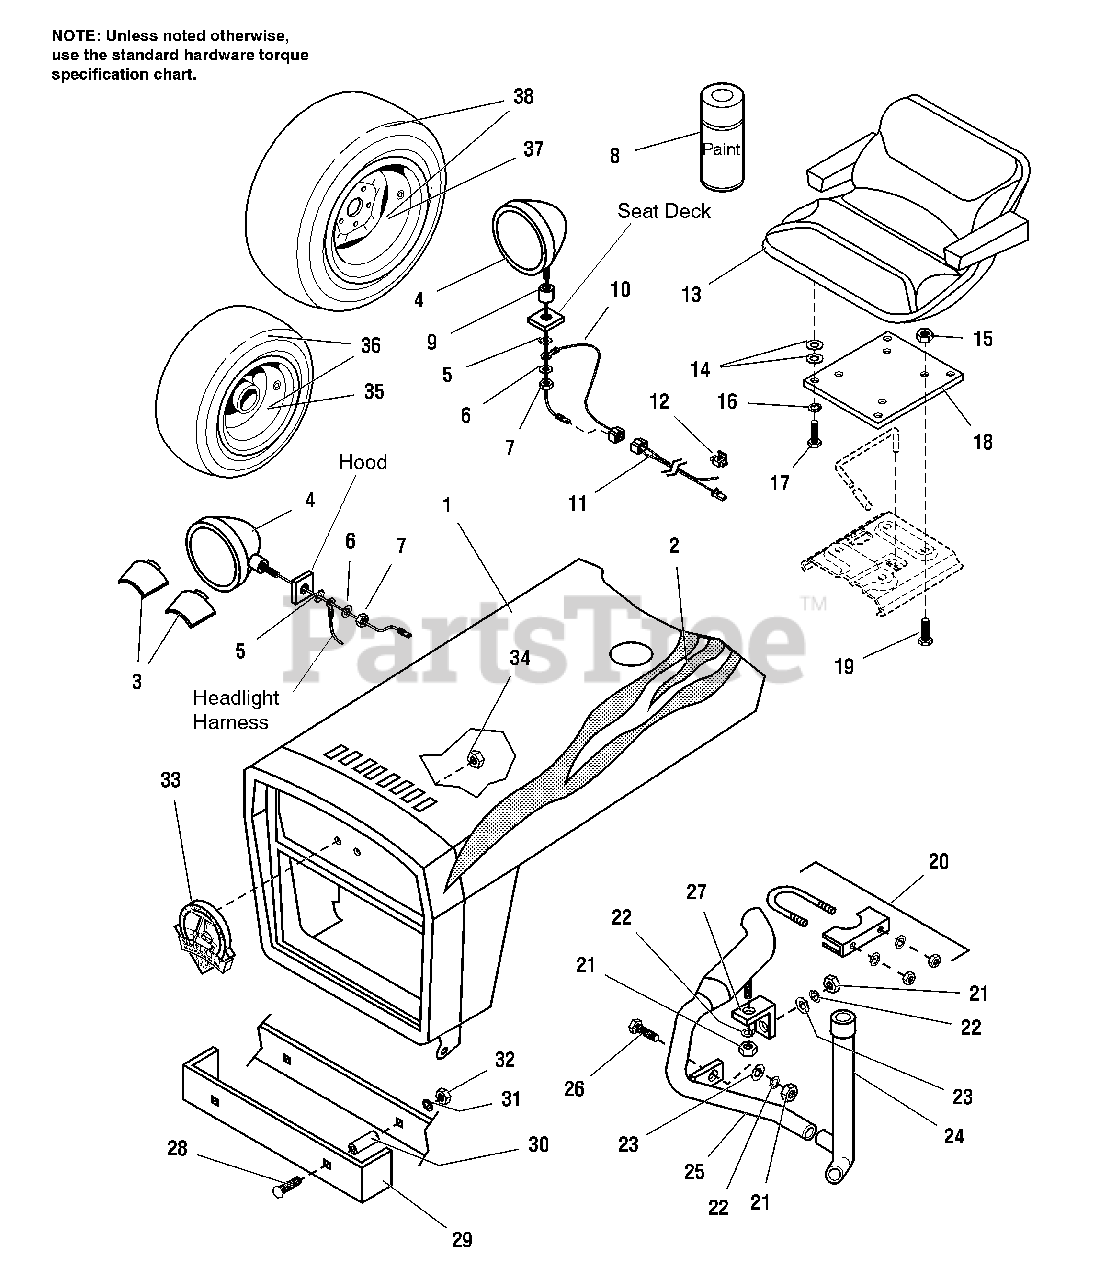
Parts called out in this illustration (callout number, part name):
1	HOOD ASSEMBLY.
2	DECAL, R.H. Hood, Flame
2	DECAL, L.H. Hood, Flame
2	DECAL, Mower
2	DECAL, Rear Seat Deck, "Simplicity"
3	VISOR SET
4	HEADLIGHT-REAR WORKLIGHT ASSEMBLY
5	LOCKWASHER, External Tooth, 3/8
6	WASHER, 3/8
7	NUT, Hex, Full, 3/8-16
8	PAINT, Single Can, 13 oz. Spray Can, Blue
8	PAINT, Case of 12 Cans, 13 oz. Spray Can, Blue
10	WIRE ASSEMBLY, Ground
11	WIRE ASSEMBLY, Work Light
12	CONNECTOR, Splice
13	SEAT ASSEMBLY, with Armrests
14	WASHER, 3/4 x 7/8 x 1/8
15	NUT, Flange, Whizlock, 5/16-18
16	LOCKWASHER, 5/16
17	CAPSCREW, Hex Hd, 5/16-18 x 7/8
18	PLATE, Seat Mounting
19	CAPSCREW, Hex Hd, 5/16-18 x 5/8
20	CLAMP ASSEMBLY
21	NUT, Hex, Full, 5/16-18
22	LOCKWASHER, 5/16
23	WASHER, 11/32
24	ELBOW PIPE, Exhaust
25	PIPE, Exhaust
26	CAPSCREW, Hex Hd, 5/16-18 x 1
27	SUPPORT, Exhaust Pipe
28	CARRIAGE BOLT, 3/8-16 x 3
31	LOCKWASHER, 3/8
32	NUT, Hex, Full, 3/8-16
33	MEDALLION, "75th"
34	NUT, Hex Nylon Lock, 10-24
35	WHEEL ASSEMBLY, Front, Chrome
36	WHEEL & TIRE ASSEMBLY, 16x6.50-8, Chrome, Turf Tread
37	WHEEL ASSEMBLY, Rear, Chrome
38	WHEEL & TIRE ASSEMBLY, 23x10.50-12, Chrome, Turf Tread
